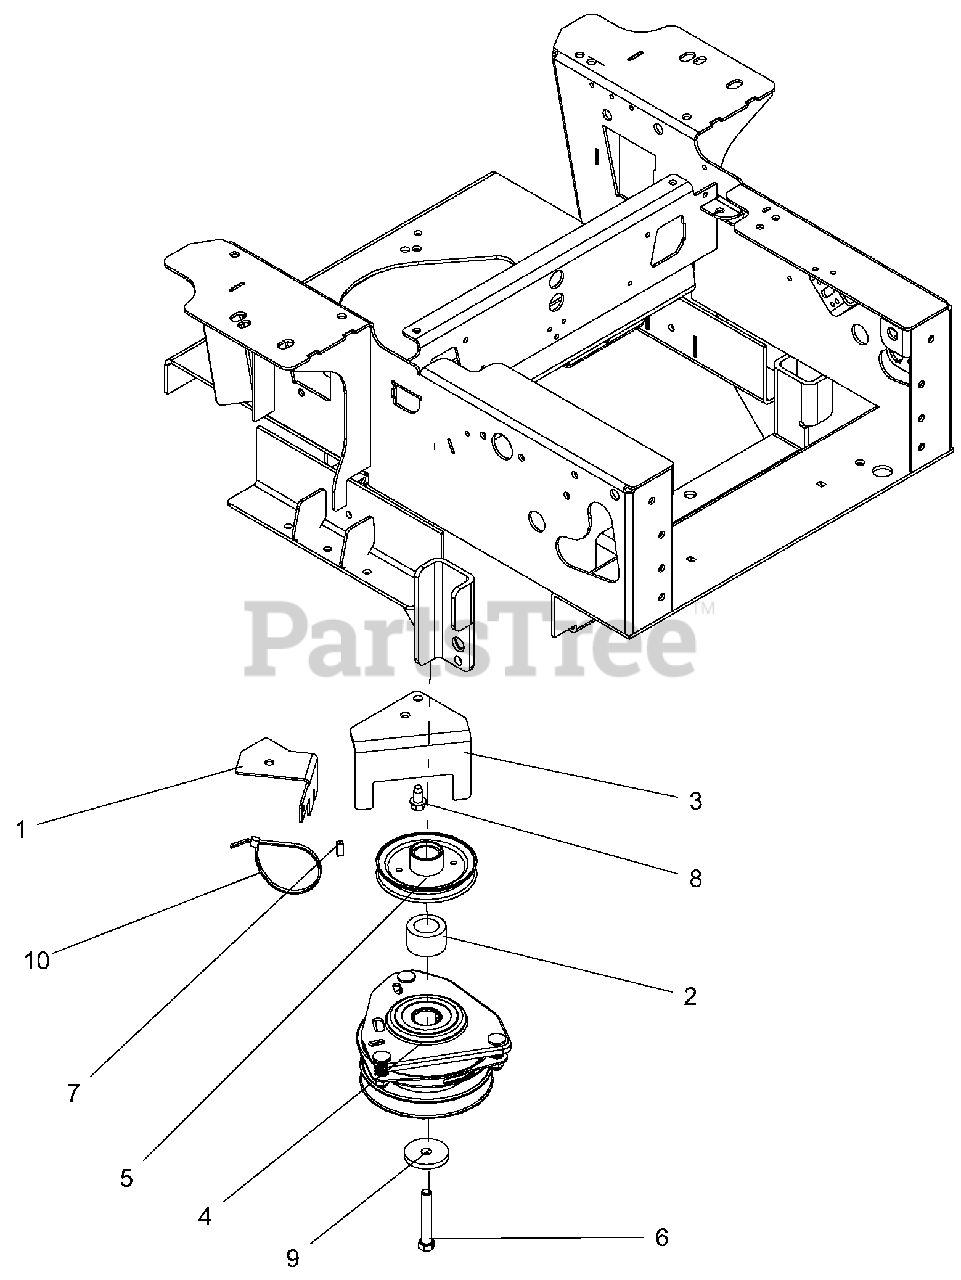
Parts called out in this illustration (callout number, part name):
1	HD CLUTCH WIRE GUARD - BLK
2	SPACER, 1.125 C 1.750 X 1.060
3	STOP, PRO-TURN CLUTCH-BLACK
4	CLUTCH, OGURA GT1A-EH01
5	PULLEY, 4.50 OD X 1.127 ENGINE-BLACK
6	BLT-HEX .44-20X2.75 GR5 EP80 YWZC
7	KEY-SQ .250X.250X.625
8	SCR-TAP .38-16X.75 HWH TR YWZ
9	WSHR-FL-STL .469X2.00X.25 YWZC
10	CABLE, TIE 5.50 LG
